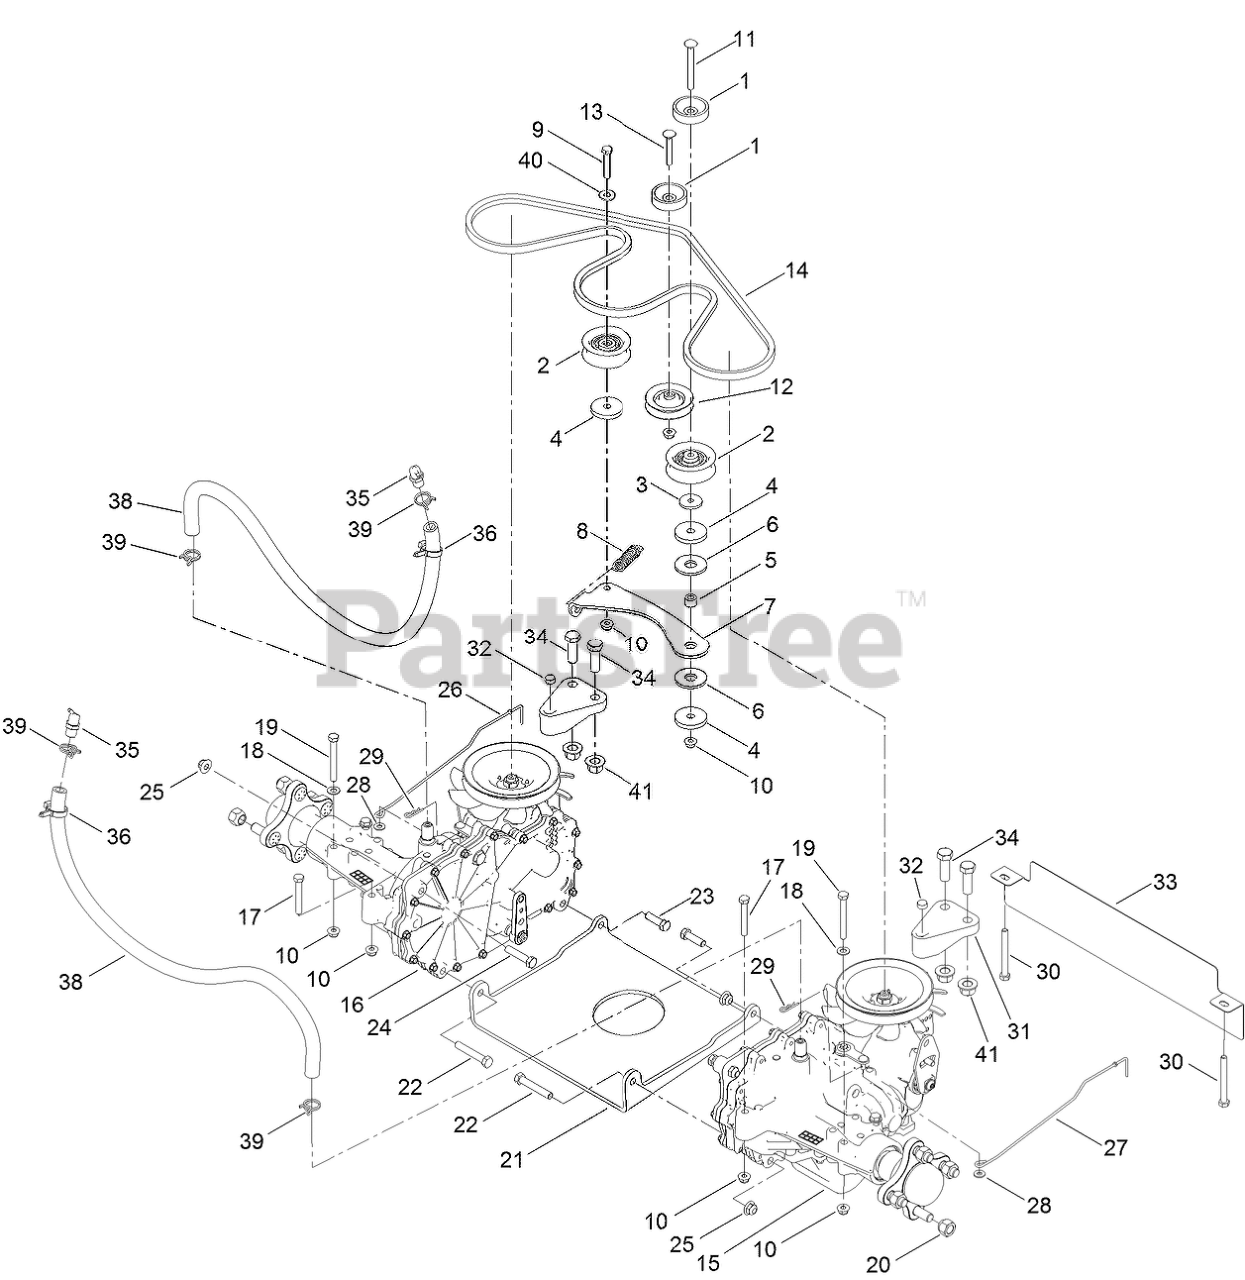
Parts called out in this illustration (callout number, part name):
1	SPACER
2	PULLEY-IDLER, FLAT
3	WASHER-FLAT
4	WASHER-PLAIN
5	BUSHING
6	WASHER-FRICTION, COMPOSITE
7	ARM-IDLER
8	SPRING-PEDAL, RETURN
9	SCREW-HH
10	NUT-HF
11	SCREW-CARR
12	PULLEY-IDLER
13	SCREW-CARR
14	V-BELT
15	LH HYDRO TRANSMISSION ASM
16	RH HYDRO TRANSMISSION ASM
17	SCREW-HH
18	WASHER-PLAIN
19	SCREW-HH
20	NUT-LUG
21	PLATE-CROSS, HYDRO
22	SCREW-HH
23	SCREW-HH
24	SCREW-HH
25	NUT-HF, NI
26	ROD-BYPASS, RH
27	ROD-BYPASS, LH
28	WASHER-FLAT
29	PIN-HAIR
30	SCREW-HH
31	SUPPORT-HYDRO, REAR
32	NUT-HEX
33	GUARD REAR, WIDE
34	SCREW-HH
35	BREATHER KIT
36	CLAMP-HOSE
38	HOSE-HYDRO
39	CLAMP-HOSE
40	WASHER-FLAT
41	NUT-HF
